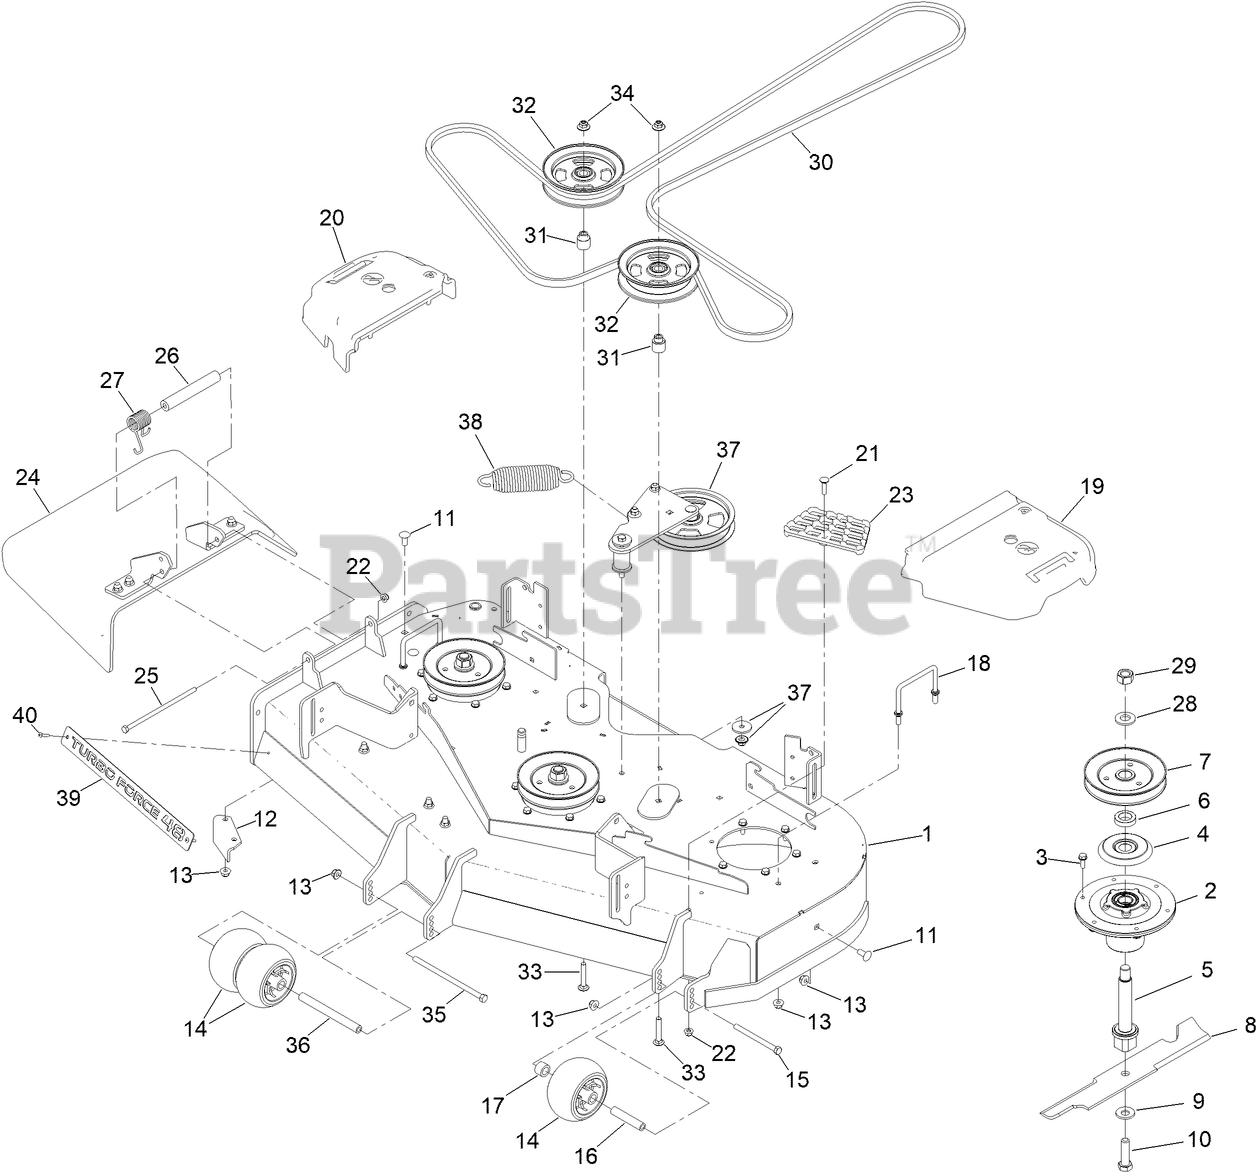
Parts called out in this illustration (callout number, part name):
1	DECK DECAL ASM
2	SPINDLE ASM
3	SCREW-TAPTITE
4	SHIELD-BEARING
5	SHAFT-SPINDLE
6	SPACER-PULLEY
7	SHEAVE,BLADE DRIVE 5.91
8	BLADE-ROTARY, 16.5IN (HI FLOW)
9	WASHER-BELLEVILLE
10	SCREW-BLADE
11	SCREW-CARR
12	BAFFLE-DISCHARGE
13	NUT-HF, NI
14	ROLLER-SCALP, ANTI
15	SCREW-HH
16	TUBE-SHAFTING
17	TUBE-SPACER
18	WIREFORM-COVER
19	COVER-BELT, LH
20	COVER-BELT, RH
21	SCREW-CARR
22	NUT-HF, NI
23	STEP-DECK
24	RUBBER DEFLECTOR ASM
25	SCREW-HH
26	SPACER
27	SPRING-TORSION
28	WASHER
29	NUT-HEX
30	BELT-V
31	BUSHING, IDLER
32	PULLEY-IDLER, FLAT
33	SCREW-CARR
34	NUT-FLANGE, NI
35	SCREW-HH
36	SPACER-WHEEL
37	IDLER ARM ASM
38	SPRING-EXTENSION
39	PLATE-TURBO FORCE [BLACK]
40	RIVET-TRIFOLD
